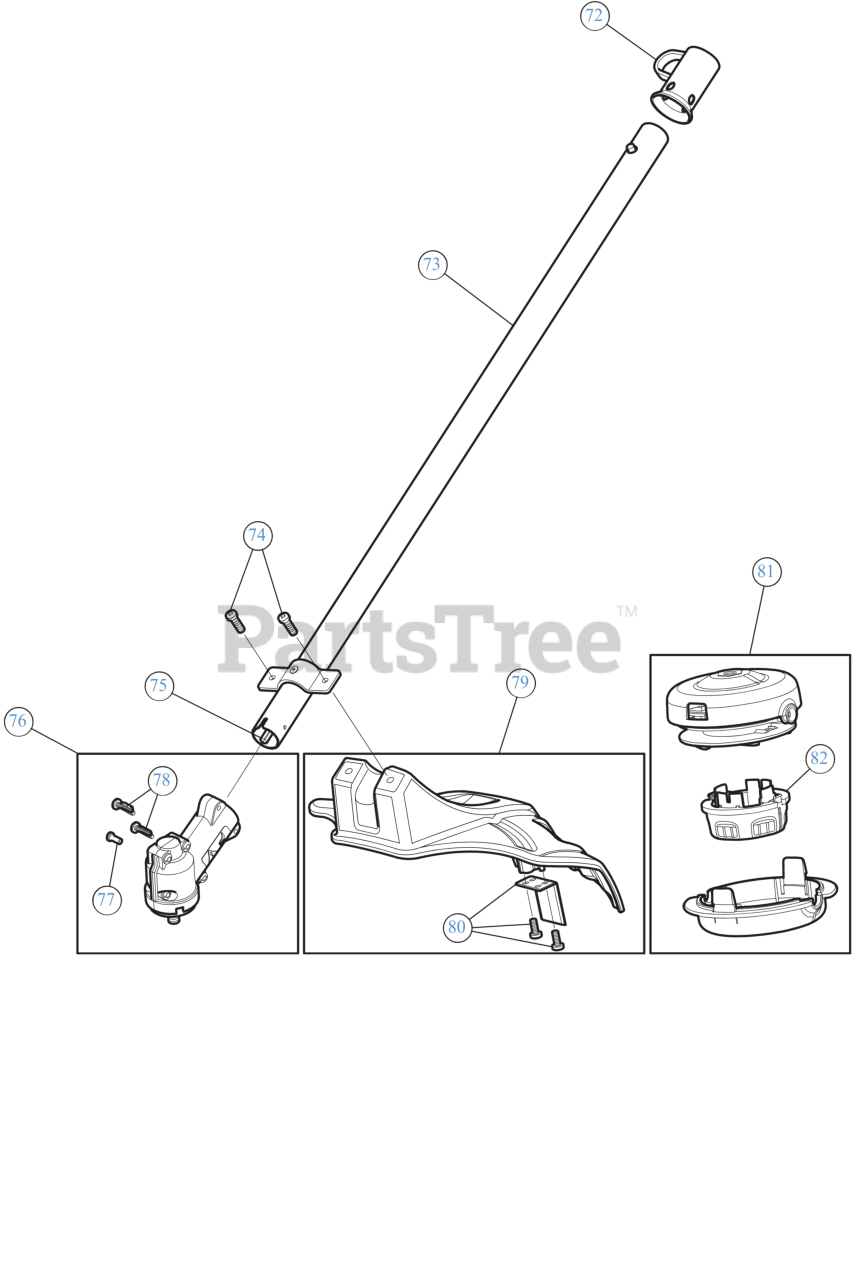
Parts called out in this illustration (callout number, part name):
73	BOOM ASSEMBLY LOWER
74	SCREW & NUTS 10X32
75	LOWERIBLE DRIVE SHAFT
76	GEARBOX LCBC
77	SCREW, 8-32 x .312 P
79	GUARD/BLADE ASSEMBLY
80	BLADE CUT OFF (LH)
81	CUTTING HEAD ASSEMBLY
82	BUMP KNOB CNT YELLOW
